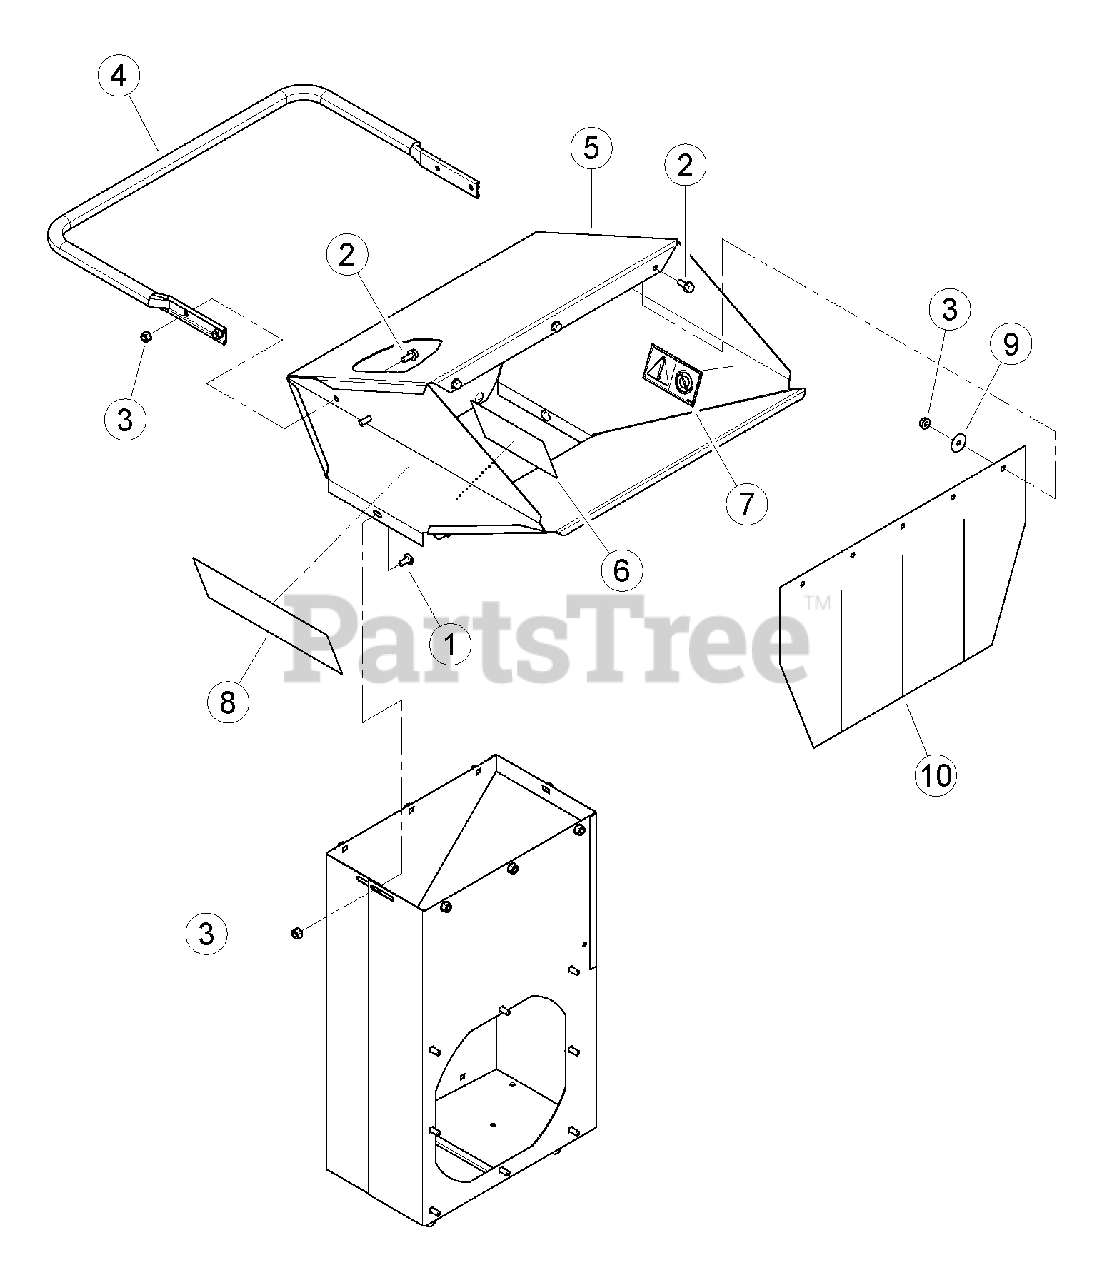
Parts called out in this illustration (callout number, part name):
1	BOLT, 5/16-18 X 3/4 CRG SN GR5
2	BOLT, 5/16 X 3/4 FLANGE NC
3	NUT, 5/16-18 NYLOCK-FLANGE
4	HANDLE, RENTAL HOPPER
5	ASSEMBLY, WIDE BODY HOPPER
6	DECAL, BLADE DANGER ISO
7	DECAL, SHREDDER SIZE ISO
8	DECAL, ECHO BEARCAT 12.00 X 4.00
9	WASHER, 5/16 FENDER ZP
10	BELTING, RENTAL HOPPER
